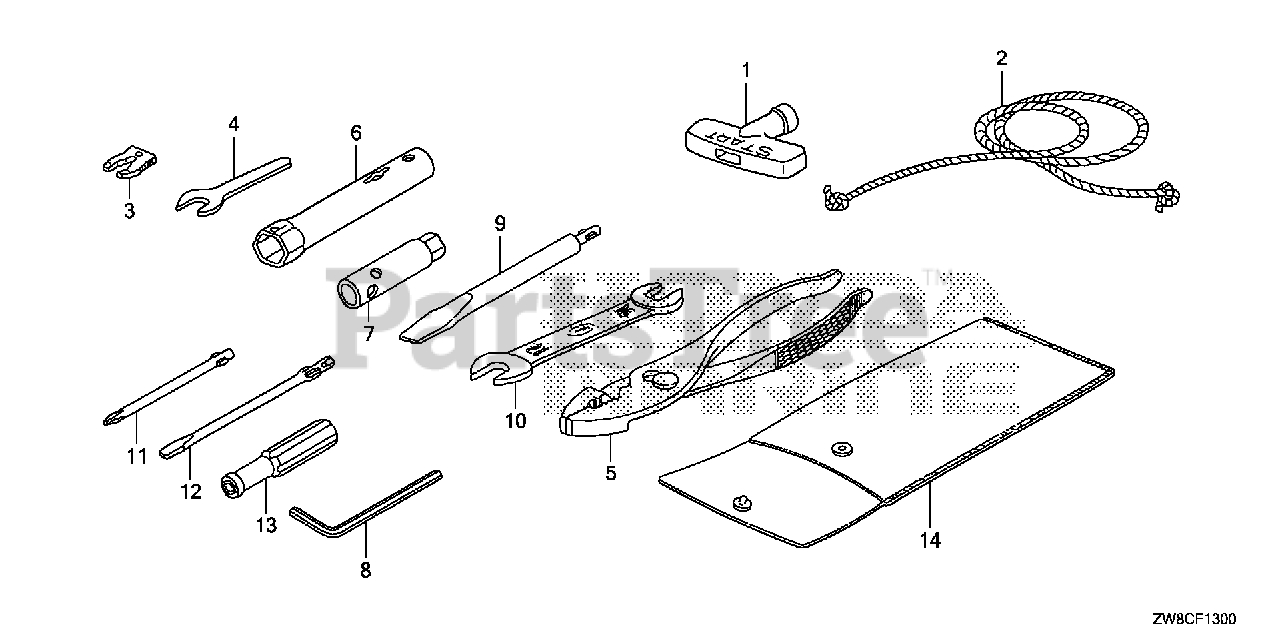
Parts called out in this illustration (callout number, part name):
1	KNOB, RECOIL SRARTER
2	ROPE, RECOIL STARTER (1300MM)
5	PLIERS (135) (RIKEN)
6	WRENCH, SPARK PLUG
7	WRENCH, BOX (10MM)
8	WRENCH, HEX. (4MM)
9	SCREWDRIVER, CHECK BOLT
10	SPANNER (10X12)
11	DRIVER 1, PLUS SCREW (NO.2)
12	DRIVER 3, MINUS SCREW (NO.2)
13	GRIP, SCREW DRIVER
14	BAG, TOOL (160MM)
